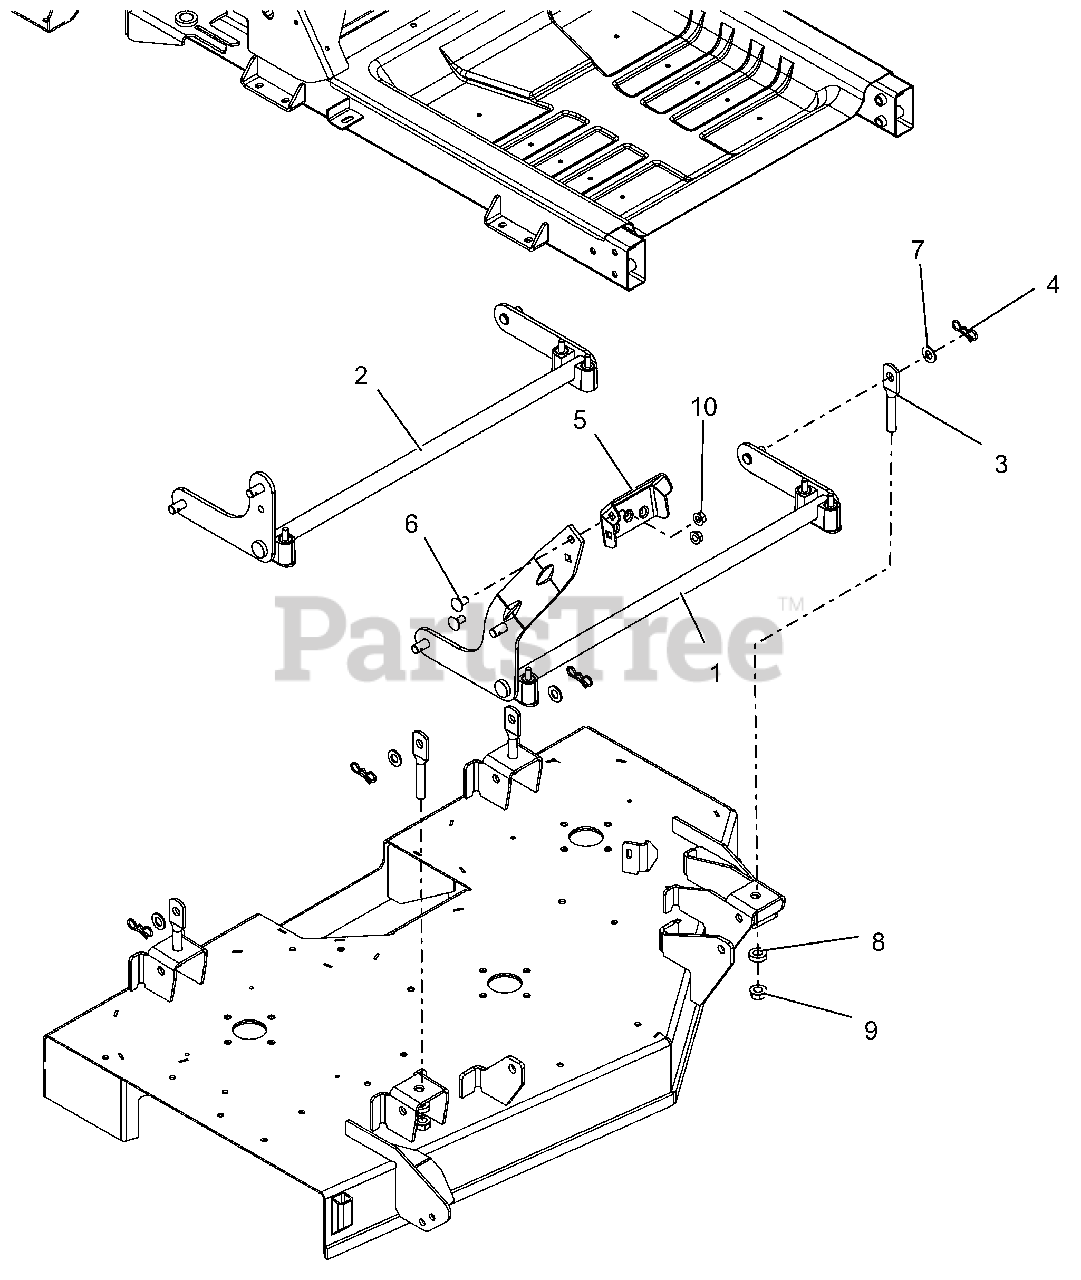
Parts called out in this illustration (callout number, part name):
1	WLDMT, FRONT DECK LIFT PIVOT
2	WLDMT, REAR DECK PIVOT
3	LINK, DECK (HOLE-SHORT)
4	PIN, BOWTIE .091X1.875 ZCC
5	PEDAL, DECK LIFT (BOLT ON)
6	BLT,RHSN .38-16X.75 G5 BFP
7	WSHR-FL-NYL .518X1.000X.080
8	WSHR, RUBBER
9	NUT-LK-CTR-FLG .500-13 GG ZCC
10	NUT-LK-CTR-FLG .375-16 GF ZCC
